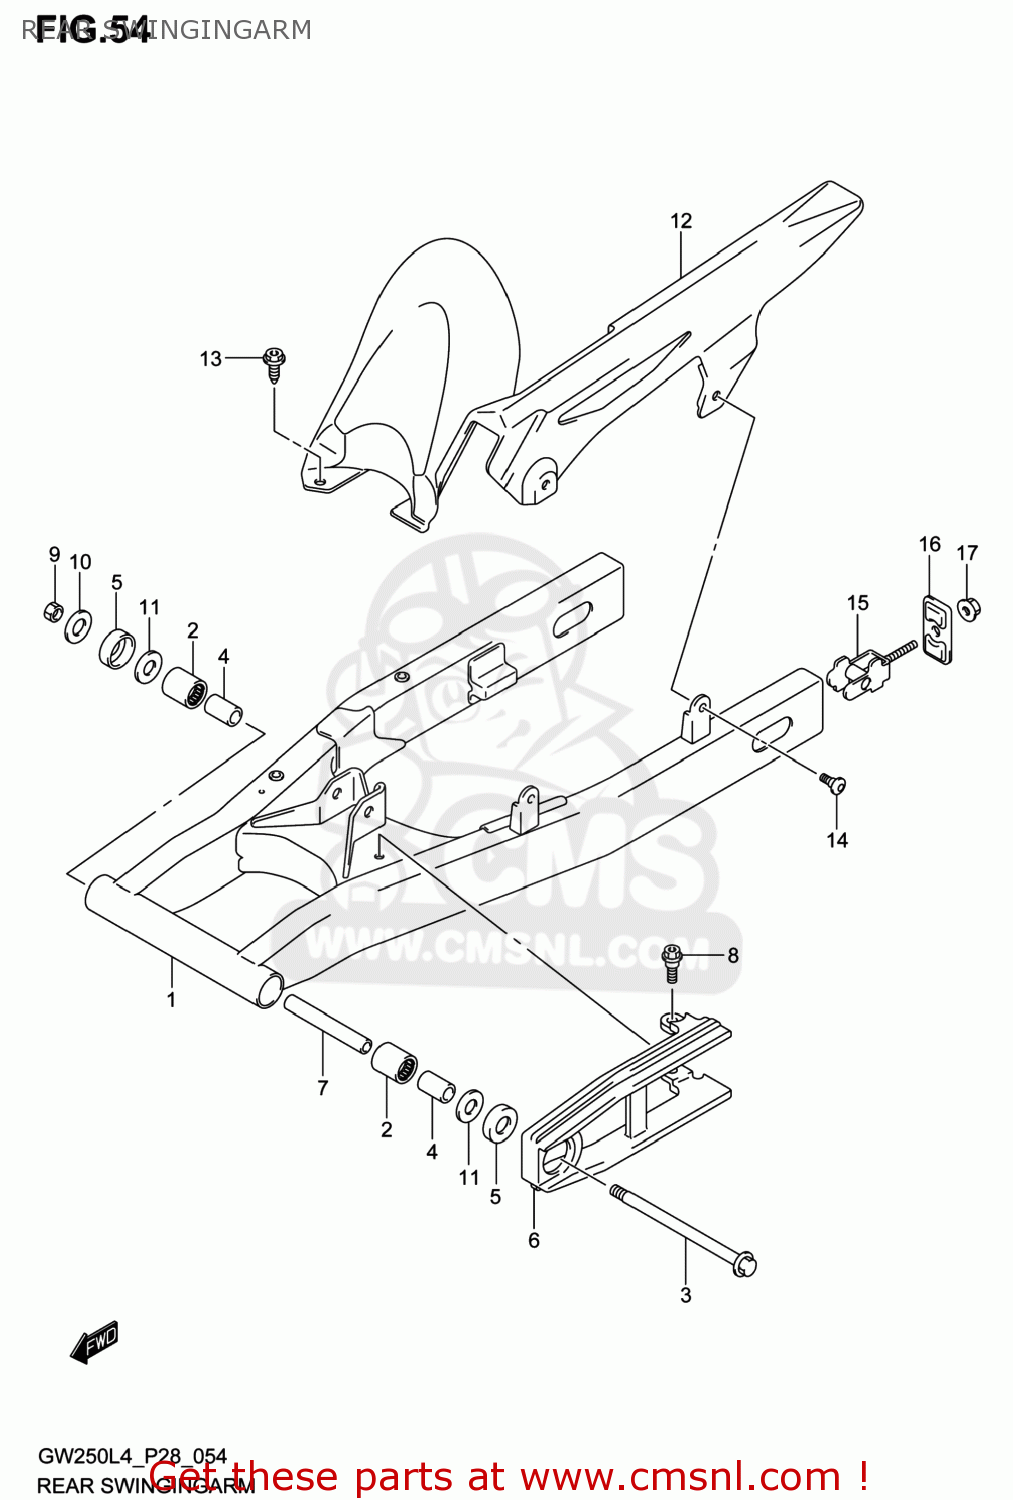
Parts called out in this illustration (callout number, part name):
1	SWINGINGARM,RR
2	BEARING(22X29X30)
3	SHAFT,RR SWINGINGARM PIVOT
4	SPACER,RR SWGARM PIVOT BEARING
5	COVER,RR SWGARM PIVOT DUST
6	BUFFER,CHAIN TOUCH DEFENSE
7	SPACER,RR SWGARM PIVOT CTR
8	BOLT(6X17.8)
9	NUT
10	WASHER(14.5X29X2.3)
11	WASHER(14X34X1)
12	CASE,CHAIN
13	BOLT(6X16)
14	SCREW(6X16)
15	ADJUSTER,CHAIN
16	PLATE,CHAIN ADJUSTER GUIDE
17	NUT
